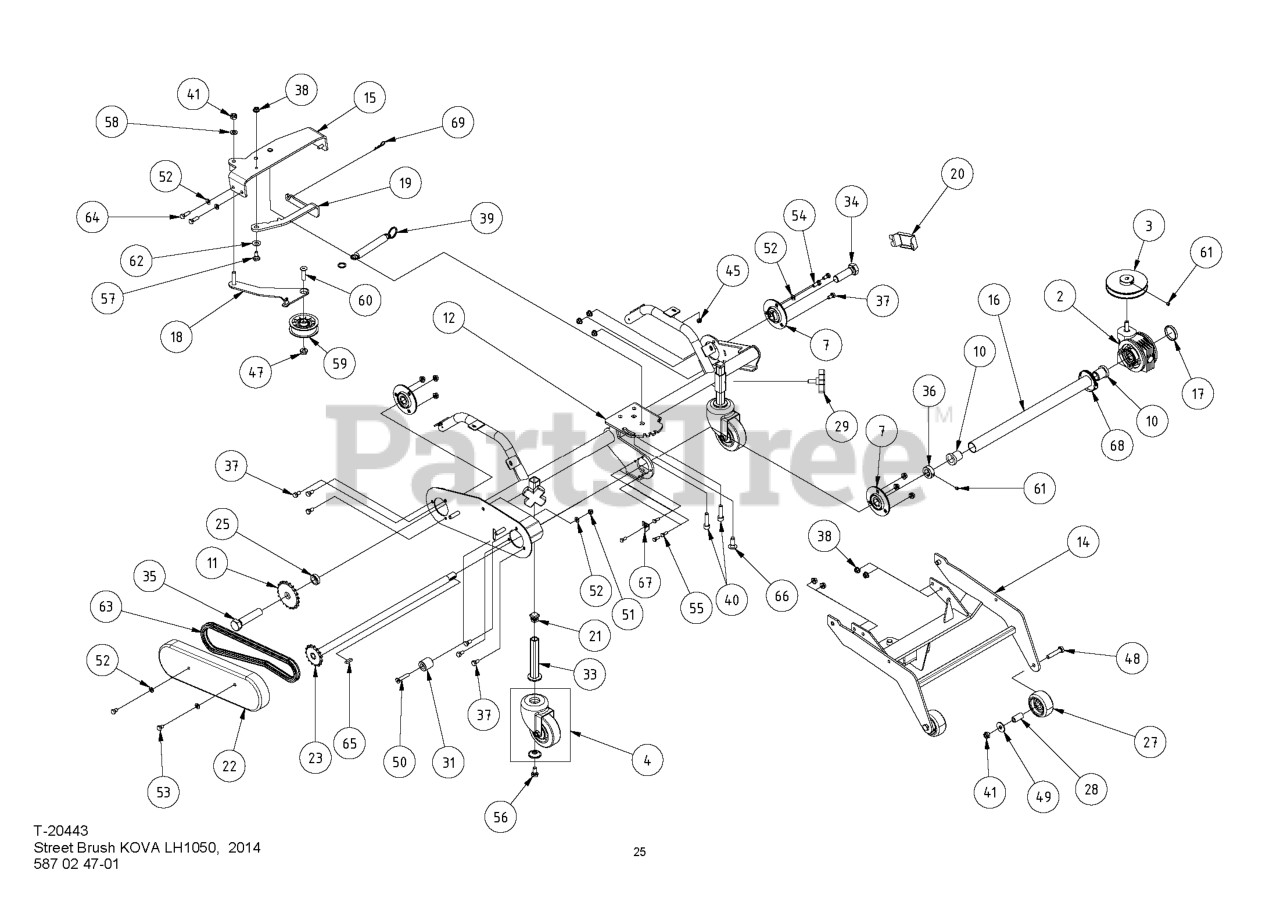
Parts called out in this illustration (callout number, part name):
4	SUPPORT WHEEL
23	DRIVE SHAFT
27	SUPPORT WHEEL
28	COLLAR
31	CHAIN ADJUSTER
38	NUT LOCKING
